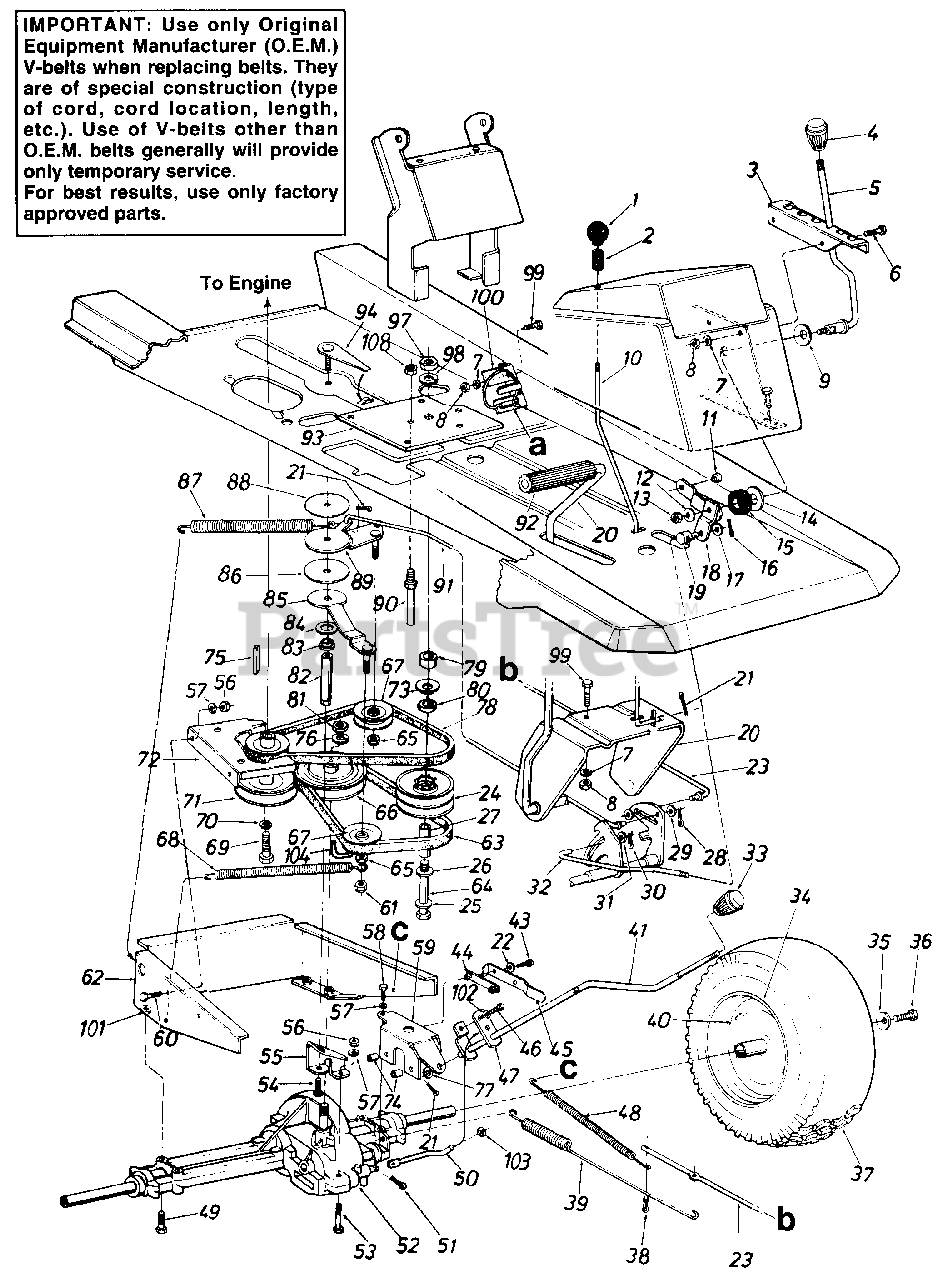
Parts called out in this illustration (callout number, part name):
1	Ball Knob 1/4-20 Thd. 1.25"
2	Compression Spring
5	Speed Control Lever
6	Truss Mach, Scr. 5/16-18 x .75" Lg.
7	L-Wash. 5/16" I.D.
8	Hex Nut 5/16-18 Thd.
9	Bell-Wash. .345" I.D. x .88"
10	Brake Locking Rod
12	Bell-Wash. .345" I.D. x .08"
13	Hex Cent. L-Nut 5/16-18 Thd.
14	Fl-Wash. .50" I.D. x 1.5" O.D.
15	Rubber Washer
16	Intern. Cotter Pin 1/2" Dia.
17	Fl-Wash. .34" I.D. x .68" O.D.
18	Speed Control Lever Brkt. Ass'y.
19	Ferrule - Engagement
20	Clutch/Brake Pedal Ass'y.
21	Cotter Pin 3/32" Dia. x .75"
22	Plastic Washer
24	Variable Speed Pulley Ass'y.
25	Fl-Wash. .4" I.D. x 1.25" O.D.
26	Thrust Brg. 1.25" O.D. x .56" I.D.
27	Spacer Sleeve 2.71"
28	Cotter Pin 1/8" Dia. x 1.25"
29	Fl-Wash. .34" I.D. x .60" O.D.
30	Intern. Cot-Pin 5/16" Dia.
31	Fl-Wash. .34" I.D. x .60" O.D.
32	Speed Control Rod
33	Shift Knob
35	Bell-Wash. .345" I.D. x .88"
36	Hex L-Bolt 5/16-24 x .75" Lg.
38	Cotter Pin 1/8" Dia. x 1.25"
39	Extension Spring 17.0" Lg.
40	Air Valve
44	Insulator Nut
45	Spring Switch
46	Hex Bolt 1/4-20 x .50" Lg.
47	Shift Lever Adjusting Link
48	Ext. Spring 8 1/4" Lg.
49	Hex Bolt 5/16-18 x 2.5" Lg.
51	Intern. Cotter Pin
52	Transaxle
53	Hex Bolt 1/4-20 x 1.75" Lg.
54	Hex Bolt 3/8-24 x .75" Lg.
57	L-Wash. 1/4" I.D.
58	Self-Tap Mach. Scr. Type "C" 1/4-20 x 1.37" Lg.
59	Shift Lever Support Brkt.
60	Hex Bolt 1/4-20 x 1.00" Lg.
61	Hex L-Nut 3/8-24 Thd.
64	Hex Bolt 3/8-16 x 4.5" Lg.
65	Hex Ins. L-Nut 3/8-24 Thd.
66	V-Pulley
67	V-Belt Idler .38" I.D. x 3.06"
68	Ext. Spring .50" O.D. x 6.37"
69	Hex Bolt 7/16-20 x 1.00" Lg.
70	L-Wash. 7/16" I.D.
71	Engine Pulley
72	Upper Eng. Belt Guard
73	Bell-Wash. .4" I.D. x 1.12" O.D.
74	Spacer .256" I.D. x .50" O.D.
75	Sq.-Key 1/4" x 2.00" Lg.
76	Bell-Wash. .567" I.D. x 1.125"
77	Fl-Wash. .469" I.D. x .88" O.D.
78	V-Belt
79	Spacer 1.00" x .380" O.D.
80	Thrust Wash. .56" I.D. x 1.25" O.D.
81	Hex Jam Nut 9/16-18 Thd.
83	Flange Bearing .378
84	Fl-Wash. .640" I.D. x 1.24"
85	Idler Bracket Ass'y.
86	Thrust Wash. .635" I.D.
87	Extension Spring 7.58" Lg.
88	Thrust Wash. .385" I.D.
89	Idler Bracket Ass'y. For Clutch
90	Belt Guard Pin 3/8-16 x 2.75" Lg.
92	Foot Pad
98	L-Wash. 3/8 Heavy Duty
99	Hex Bolt 5/16-18 x .75" Lg.
100	Speed Control Rod Brkt.
101	Hex Sems Nut 5/16-18 Thd.
102	Bell-Wash. .265" I.D. x .75" O.D.
103	Push On Retaining Ring
108	Hex Top L-Jam Nut 3/8-16 Thd.
